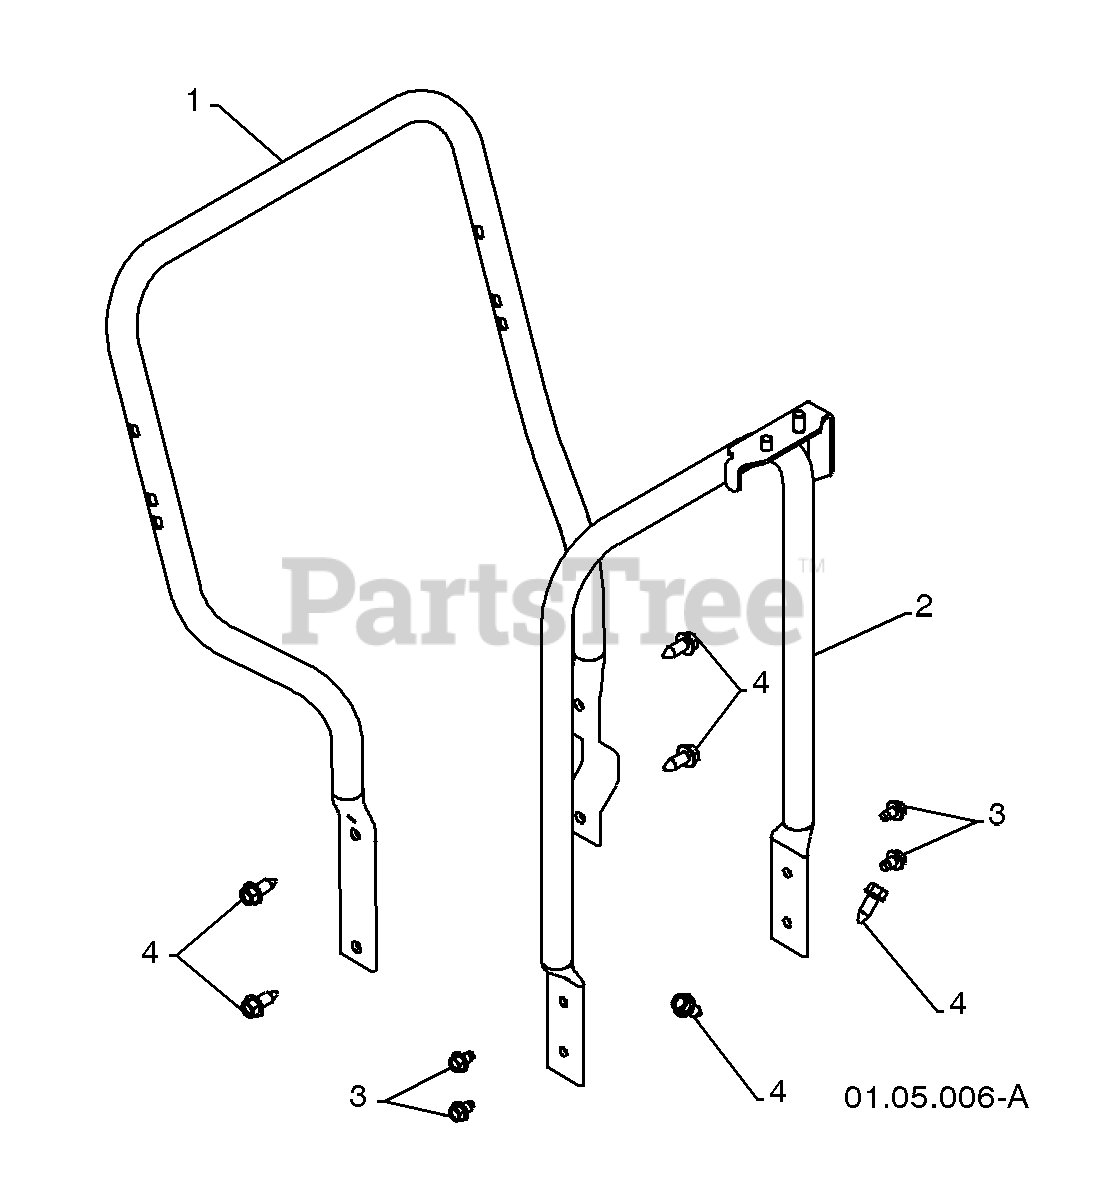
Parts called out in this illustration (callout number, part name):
1	LOWER TUBE GRAY
2	PIVOT SUPPORT
3	BOLT 5/16-18 X .500
4	SCREW 3/8-16 X 1.00
